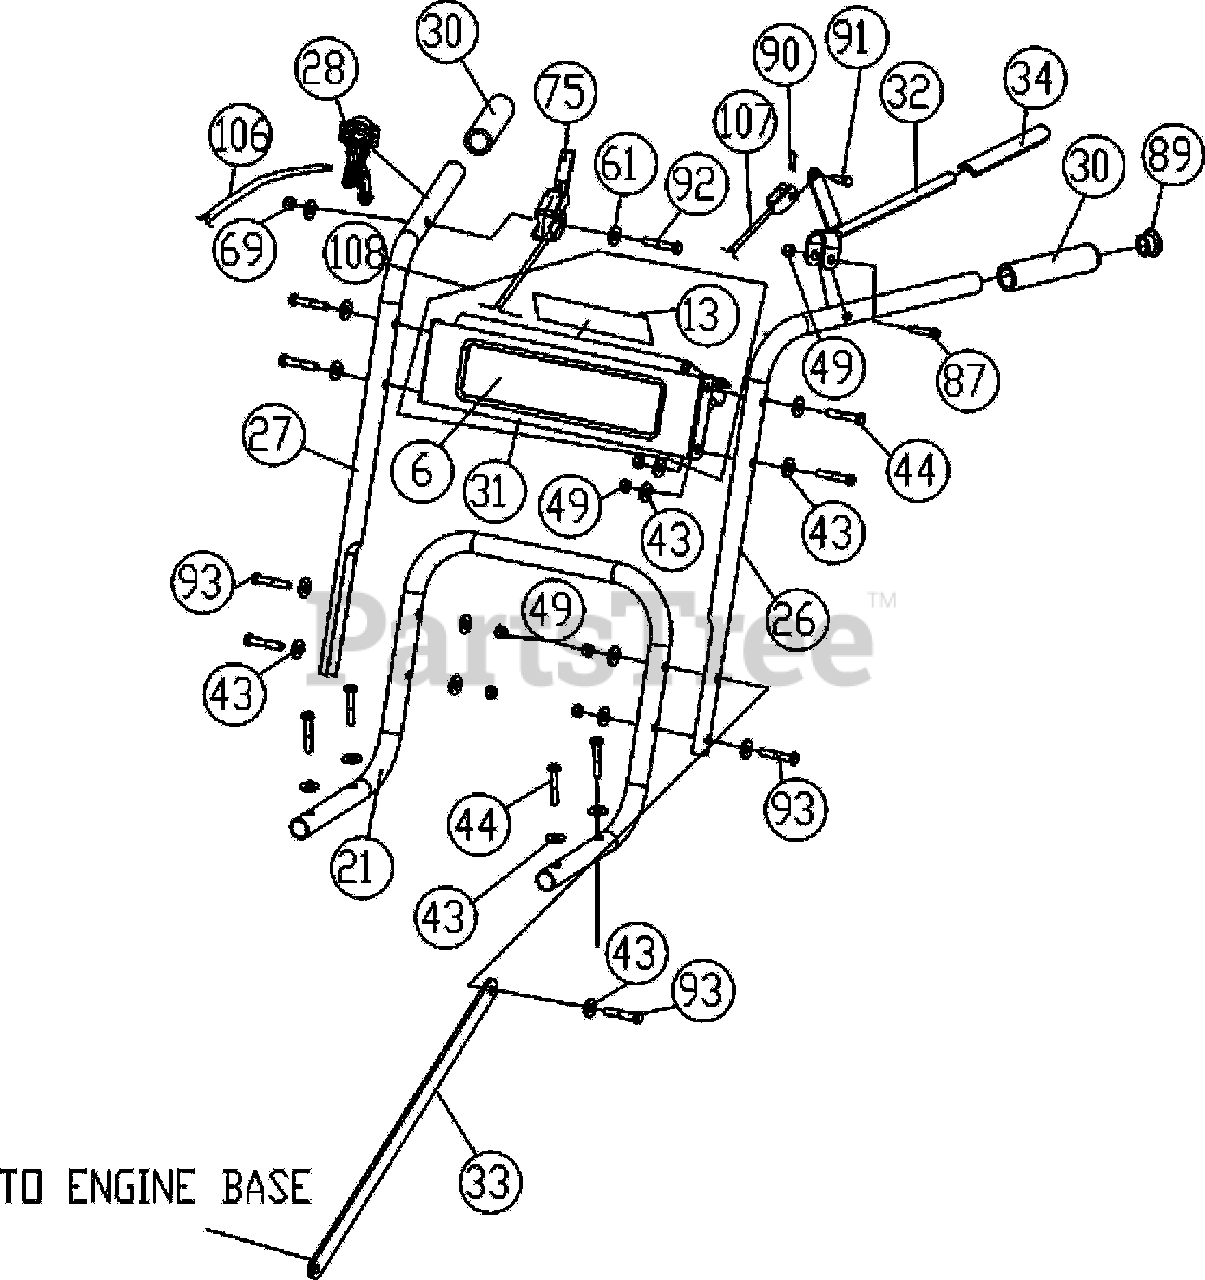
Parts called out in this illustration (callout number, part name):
6	Label Logo HP
13	Label Instruction HP
21	Handle Lower HP
26	Handle Upper LH HP
27	Handle Upper RH HP
28	Lever Control Drive HP
30	Grip Handle
31	Console WA HP
32	Lever Blade HP
33	Brace Handle HP
34	Grip Lever Orange
43	Washer 5/16 Flat ZP
44	Screwcap 5/16-18 x 1/4" HEX ZP
49	Nut Lock 5/16-18 HEX ZP
61	Washer 1/4" SAE
69	Nut Lock 1/4 - 20 HEX ZP
75	Cable Control Throttle
87	Bolt Shoulder 3/8" x 1 1/4"
89	Plug Tube Insert 1" OD
90	Pin Clip Hitch .051 x 3/4"
91	Clevis Pin 0.25 x 0.50"
92	Screwcap 1/4-20 x 2 1/4" HCS ZP
93	Screwcap 5/16-18 x 2" HCS ZP
106	Cable Clutch Wheel HP
107	Cable Clutch Blade HP
108	Console WA HP w/labels
